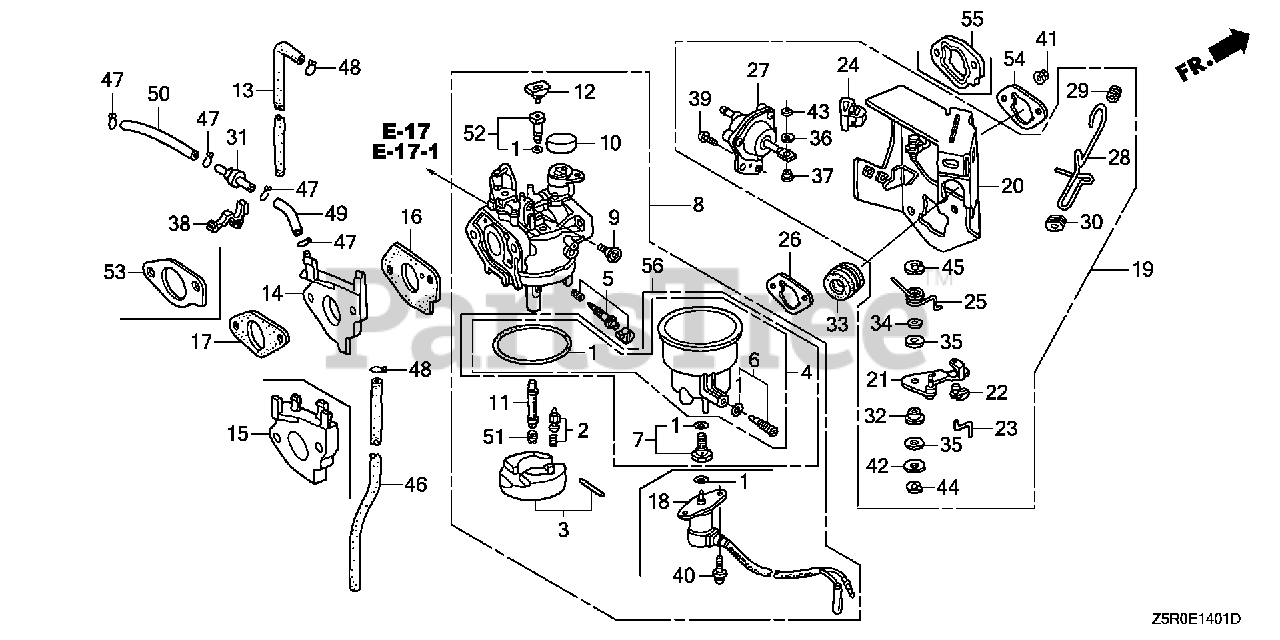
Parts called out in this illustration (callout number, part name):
1	GASKET SET
2	VALVE SET, FLOAT
3	FLOAT SET
3	FLOAT SET (CARBURETOR NO.)
4	CHAMBER SET, FLOAT
5	SCREW SET
6	SCREW SET, DRAIN (ADVENTURE GREEN) (CARBURETOR NO.)
7	SCREW SET B
8	CARBURETOR ASSY. (BE89C B)
8	CARBURETOR ASSY. (BE84B B)
9	SCREW, THROTTLE STOP
10	CAP, CHOKE LEVER DUST
11	NOZZLE, MAIN
12	COLLAR, SET
14	INSULATOR, CARBURETOR
16	GASKET, CARBURETOR
18	VALVE ASSY., SOLENOID
19	STAY ASSY., MANUAL CHOKE
20	STAY, SOLENOID
21	LEVER, CHOKE
22	JOINT, ROD
23	ROD, CHOKE
24	STOPPER, CHOKE ROD
25	SPRING, MANUAL CHOKE
26	GASKET, AIR CLEANER
27	DIAPHRAGM ASSY.
28	ROD, CHOKE CONTROL
29	GROMMET, CHOKE ROD
30	GUIDE, CHOKE ROD
31	VALVE, DASHPOT CHECK
32	BUSH, ARM PIVOT
33	GROMMET, FENDER
34	WASHER, CHOKE LEVER
35	SEAL, CHOKE LEVER
36	WASHER, THRUST (2.7X8)
37	COLLAR, LEVER
38	CLIP, WIRE HARNESS
39	SCREW, PAN (5X12)
40	SCREW-WASHER (5X12)
41	NUT, FLANGE (6MM)
42	WASHER, PLAIN (5MM)
43	E-RING (2MM)
44	E-RING (4MM)
45	E-RING (7MM)
47	CLIP, TUBE (B7)
49	BULK HOSE, VACUUM (3.5X8000) (3.5X130)
50	BULK HOSE, VACUUM (3.5X8000) (3.5X130)
51	JET, MAIN (#98) Use from Engine SN BE87A A to BE87A A.
51	JET, MAIN (#100) Use from Engine SN BE87A A to BE87A A.
51	JET, MAIN (#102) (ADVENTURE GREEN) (CARBURETOR NO.)
51	JET, MAIN (#95)
52	JET SET, PILOT (#45)
53	GASKET, CARBURETOR INSULATOR
54	GASKET, AIR CLEANER
55	SPACER, CARBURETOR
